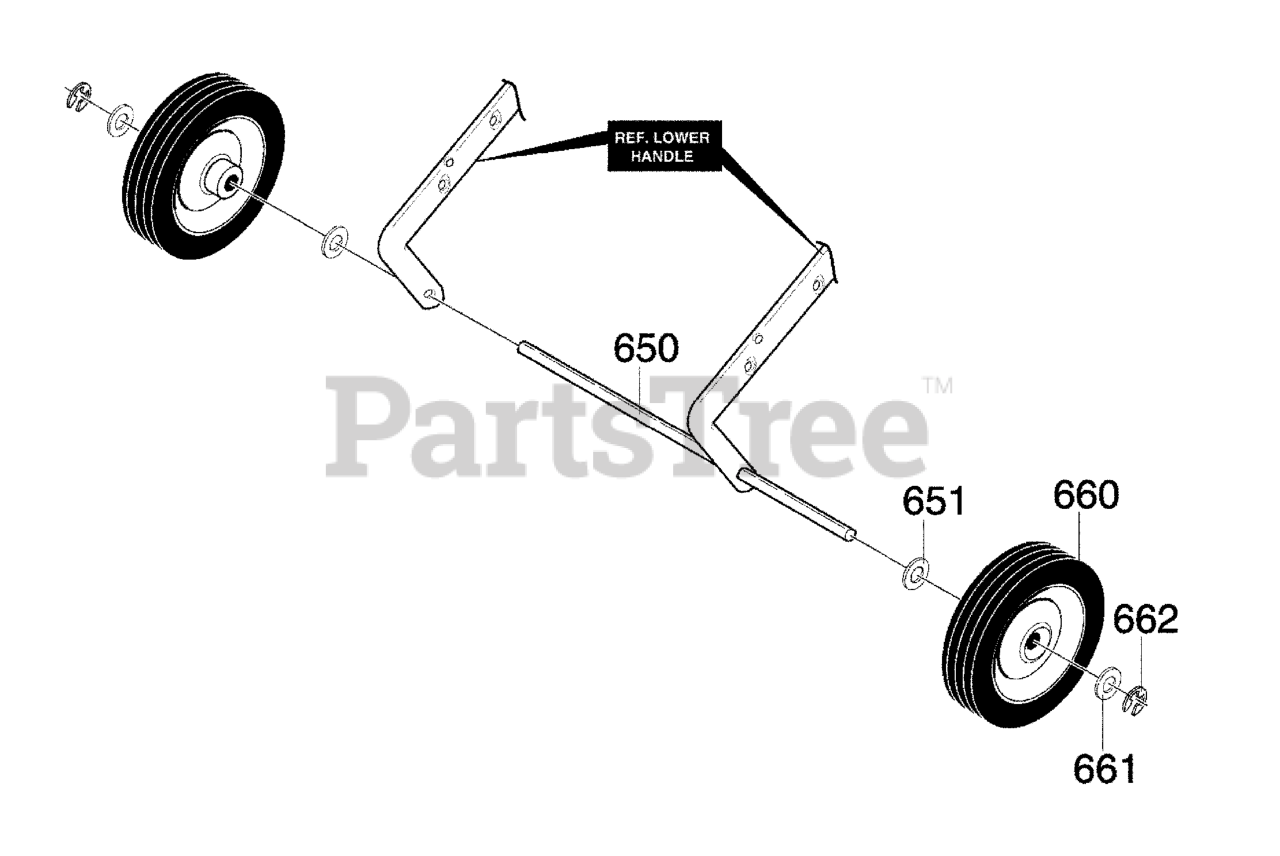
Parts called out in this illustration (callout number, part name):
650	AXLE SHAFT
651	WASHER, FLAT .391X1.00X1.25
660	TIRE & RIM
661	WASHER, FLAT .391X1.00X.125
662	RING, RET E
